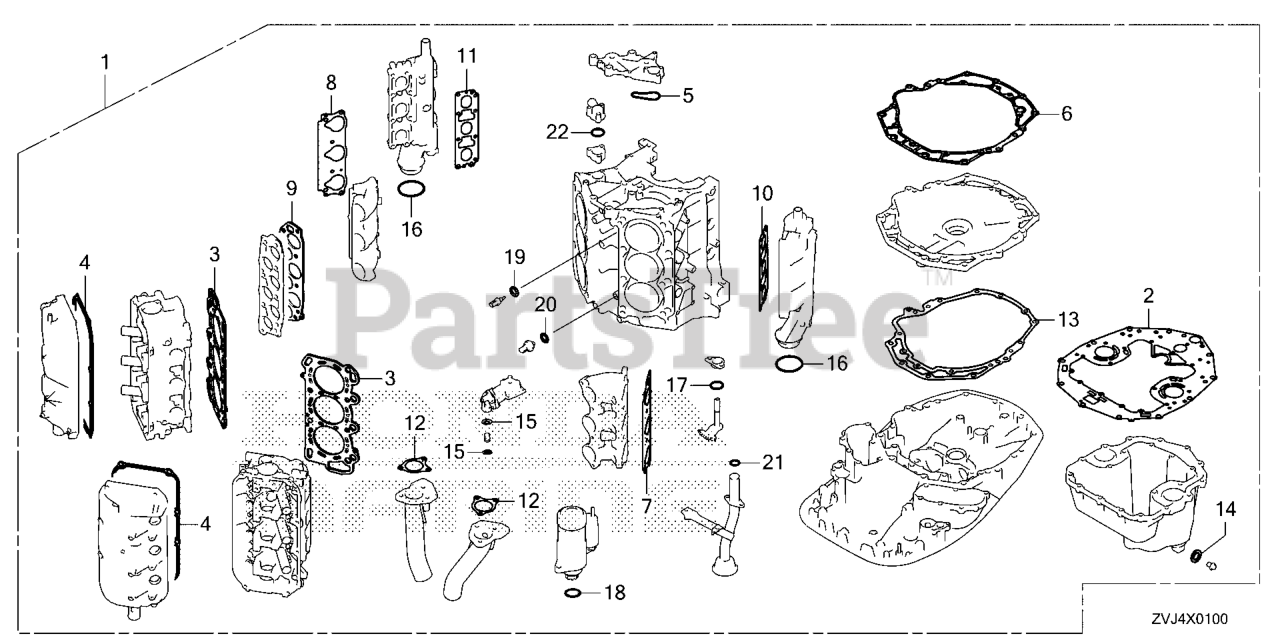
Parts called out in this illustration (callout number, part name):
3	GASKET, CYLINDER HEAD (NIPPON LEAKLESS)
4	GASKET, HEAD COVER
5	O-RING, TIMING BELT TENSIONER BASE
6	GASKET, OIL PUMP BODY
7	GASKET, FR. INJECTOR BASE
8	GASKET, RR. INJECTOR BASE
9	GASKET, IN. MANIFOLD
10	GASKET, R. EX. MANIFOLD
11	GASKET, L. EX. MANIFOLD
12	GASKET, EX. PIPE
13	GASKET, MOUNT CASE
14	WASHER, DRAIN PLUG (12MM)
15	O-RING (7.8X1.9) (ARAI)
16	O-RING (66.4X3.1)
17	O-RING (26.9X2.4) (NOK)
18	O-RING (59.4X3.1)
19	O-RING (9.5X1.9)
20	O-RING (13X1.5) (ARAI)
21	O-RING (20.6X2.6)
22	O-RING (31.5X2.4) (ARAI)
